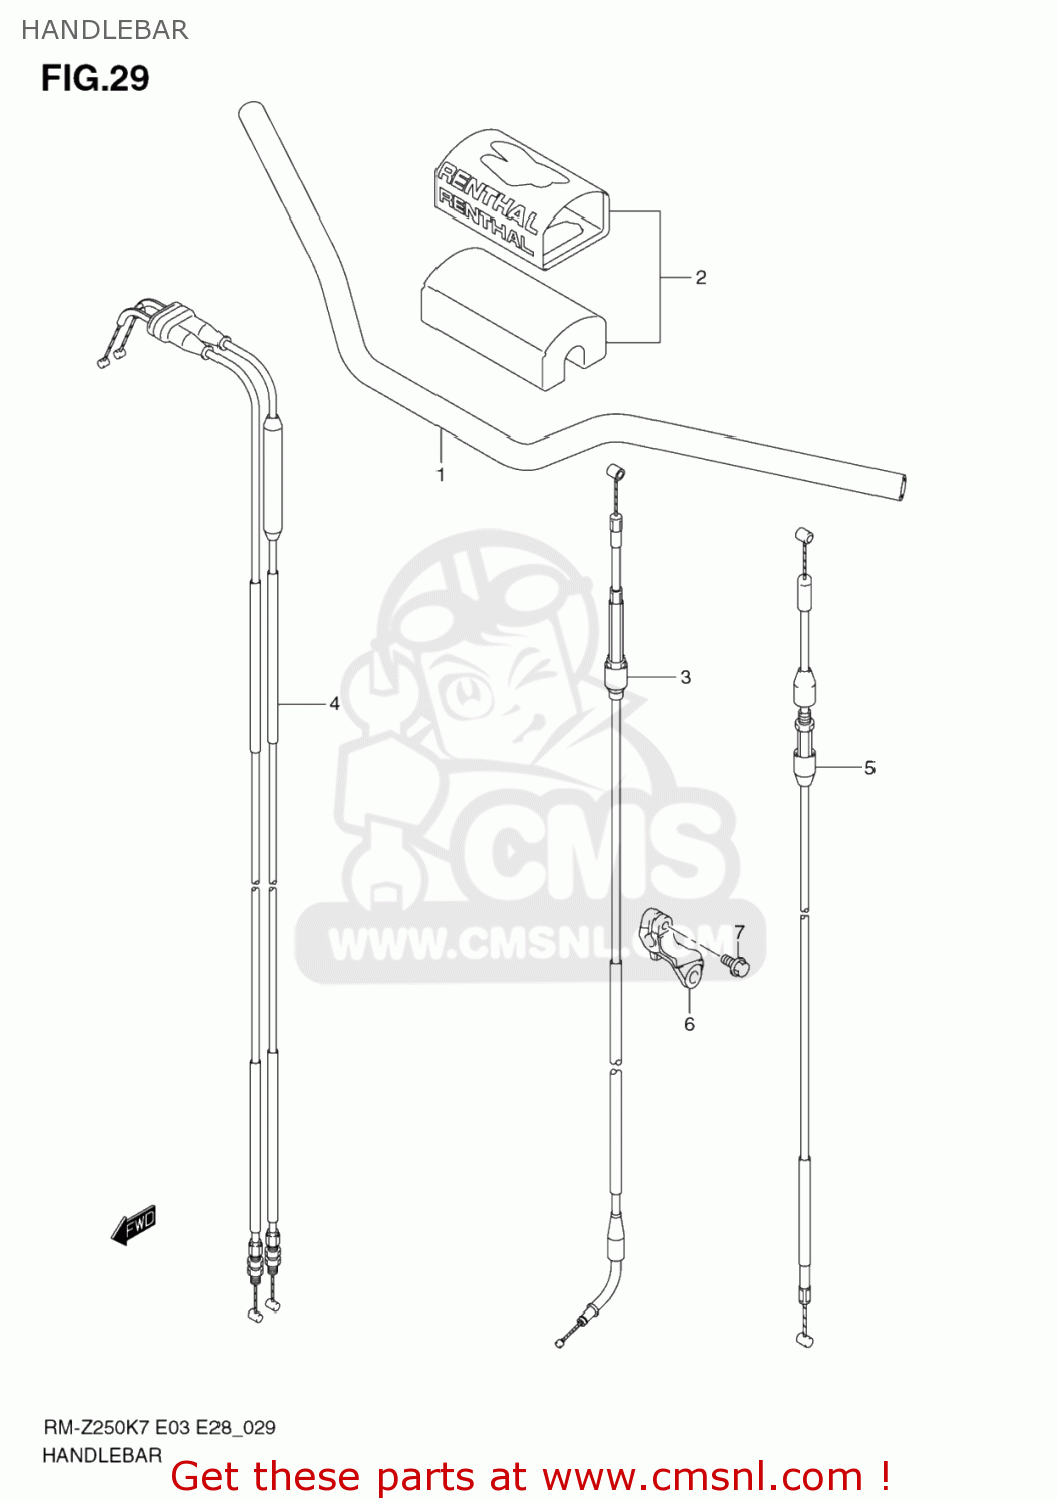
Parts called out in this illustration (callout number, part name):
1	HANDLEBAR
2	PAD SET,HANDLEBAR (NAS)
3	CABLE ASSY,CLUTCH
4	CABLE SET,THROTTLE
5	CABLE ASSY,HOT STARTER
6	BRACKET,CLUTCH CABLE
7	BOLT(6X12)
